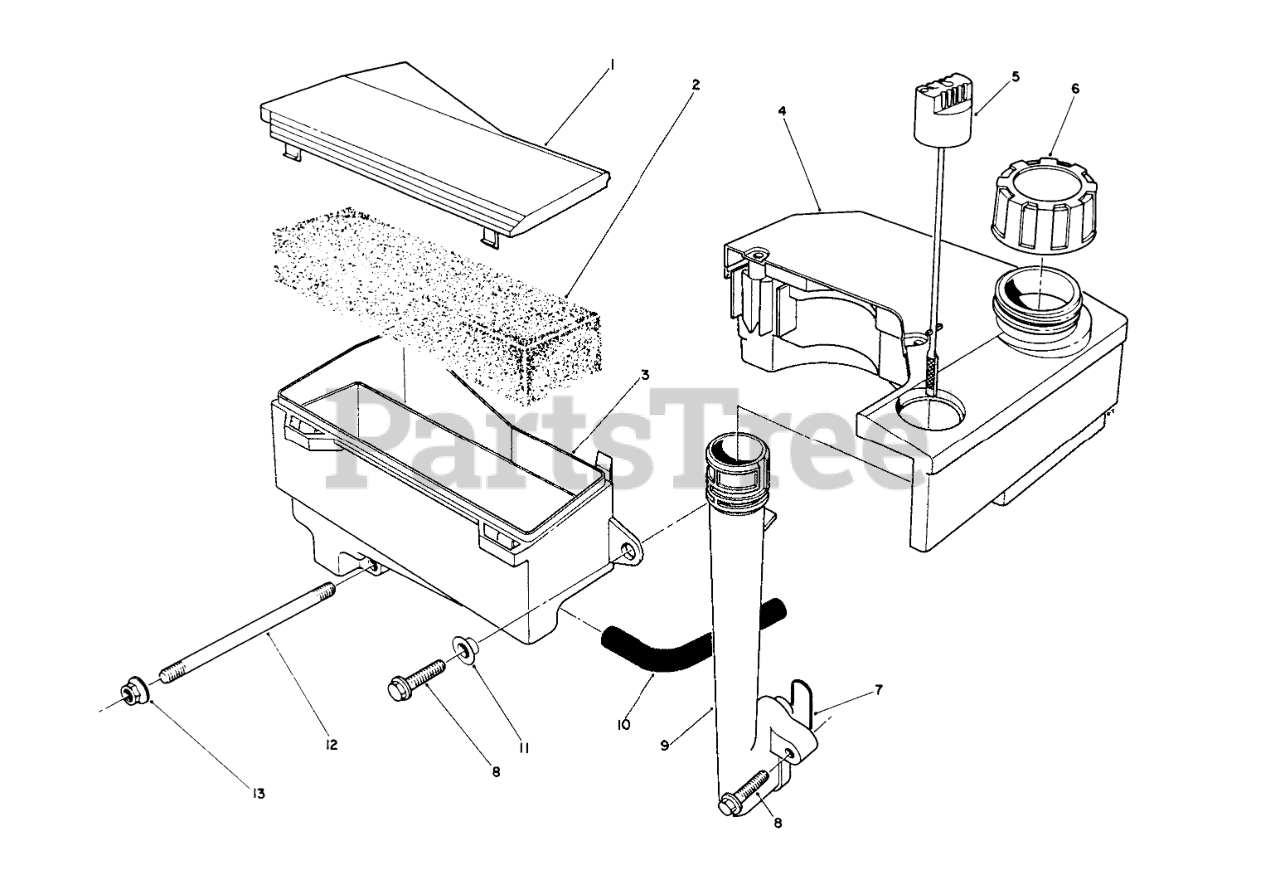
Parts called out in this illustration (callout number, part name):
1	AIR CLEANER CAP
3	Body-Air Cleaner
4	TANK ASM
5	Dipstick
6	GAS CAP ASM
7	O-RING
11	SPACER
12	Stud-Carburetor
